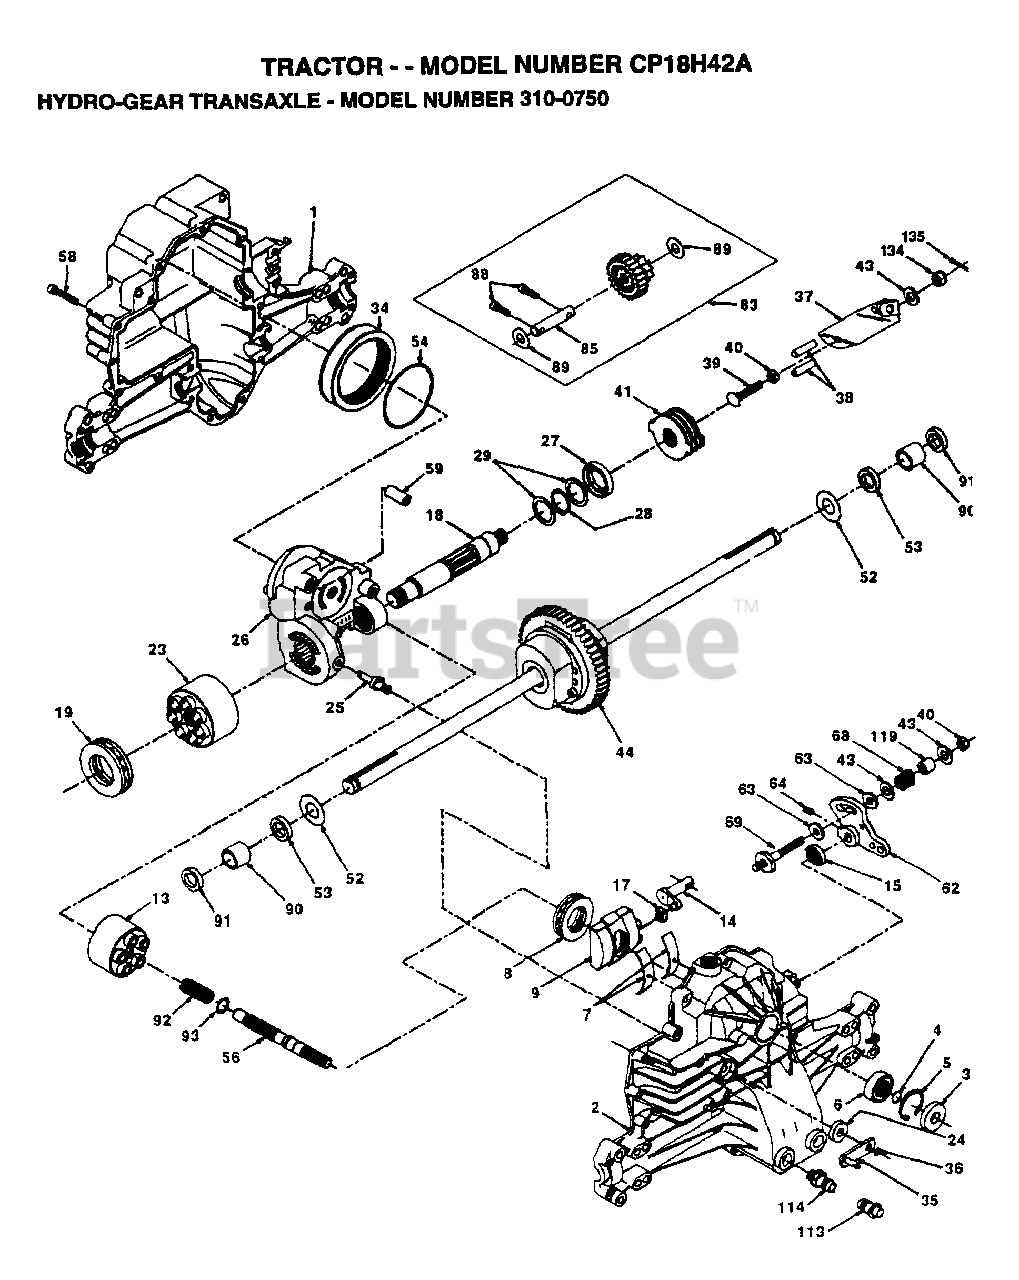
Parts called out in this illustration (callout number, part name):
1	HOUSING.L.50074RM
2	HOUSING.UP.70125
3	SEAL.9008000-0128
4	RING.RET.2003016.
5	RING.RET.2003052.
6	BEARING.(50552)42X68X16
7	CRADLE- 2003023.
8	BEARING.2003044.
9	SWASHPLT.2003087.
13	BLOCK.CLYN.70079.
14	ARM.TRUN.2003005.
15	SEAL.9008000-0126
17	GUIDE.2000015.
18	SHAFT.MOTOR.50115
19	BEARING.THS.50019
23	BLOCK.CYLIN.70082
24	SEAL.LIP.45074
25	ACTUATOR.2003555
26	KIT.CENTER.70133
27	SEAL.LIP.45075
28	RING RETAIN 50007
29	WASHER.44872
34	ELEMENT.OIL.44964
35	ARM.BYPASS.50270
36	RING.RETAIN.44870
37	ARM.ACTUAT.23710
38	PIN.ACTUAT.44891
40	NUT.LOCK.HX.50108
41	KIT.BRAKE.70135
43	WASHER HYD 44130
44	DIFFERENTIA.70130
52	WASHER.HYD.50152
53	SEAL.HYDRO.45076
54	O RING.HYD.45077
56	SHAFT.INPUT.50005
58	BOLT.1/4-20.44876
59	PIN.HYDRO.50002
62	ARM.CONTROL.50254
63	PUCK.DAMPER.50281
64	SCREW.SET.50018.
68	SPRING.HYD.50277
69	STUD.5/16-24.DANA
83	JACKSHAFT/PINION GEAR.70132
85	JACKSHAFT.50086
88	SCREW.CAP.50154.
89	WASHER.HYD.50132
90	BEARING.SLV.50118
91	SEAL.WIPER.50941
92	SPRING.2003014.
93	WASHER.2003017
113	CAP.VENT.70109
114	O-RING.ASM.70110
119	SPACER.HYD.50278
134	NUT.CAS.HYD.44142
135	PIN.COT.HYD.44101
